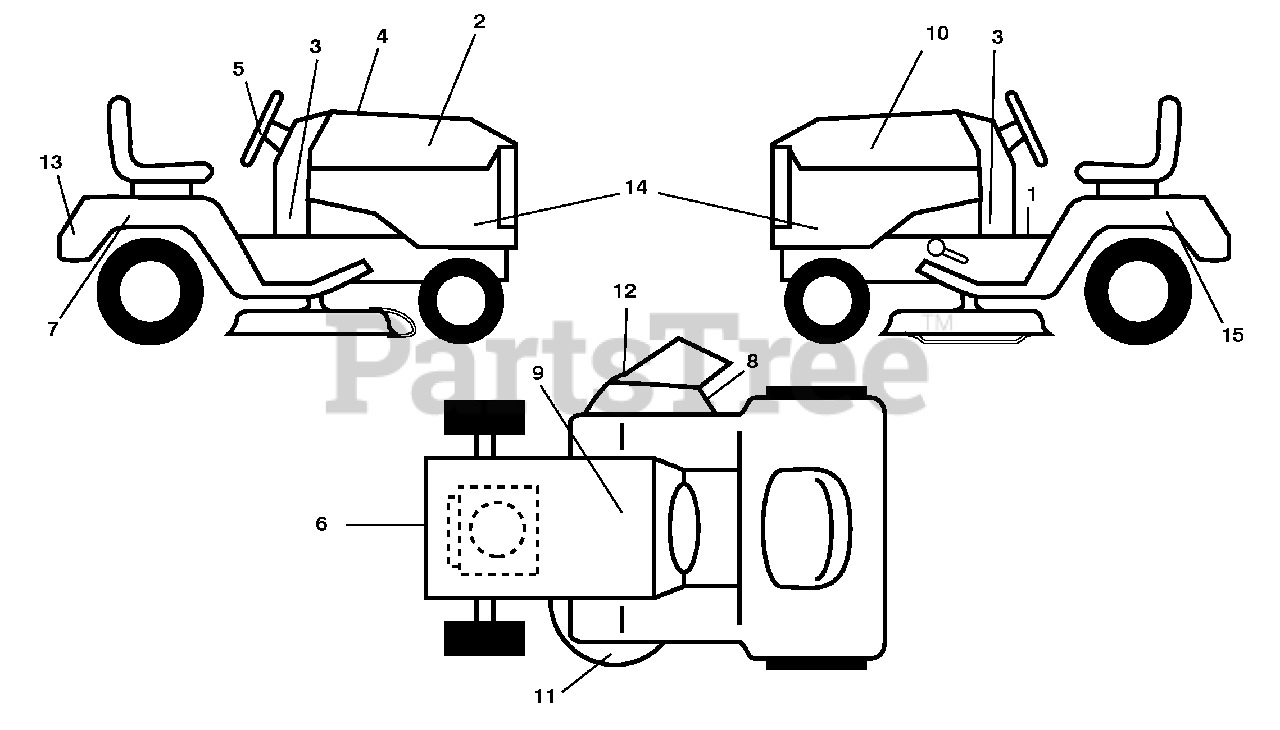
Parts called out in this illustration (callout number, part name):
1	Decal, Operator's
2	Decal, Hood RH
3	Decal, Dash Lower
4	Decal, Replacement
5	Decal, Strg Whl
6	Decal, Engine HP
7	Decal, Fender SD RH
8	Decal, Mower Sch.
9	Decal, Battery Dnge/Poi
10	Decal, Hood LH
11	Decal, Mower Caution
12	Decal, Mower Warning Keep Hand Away
13	Decal, Fender
14	Decal, Panel SD
15	Decal, Fender SD LH
15	Decal, Bypass
15	Pad, Footrest, LH
15	Pad, Footrest, RH
15	Manual, Operator's (Eng & French)
15	Manual, Parts
